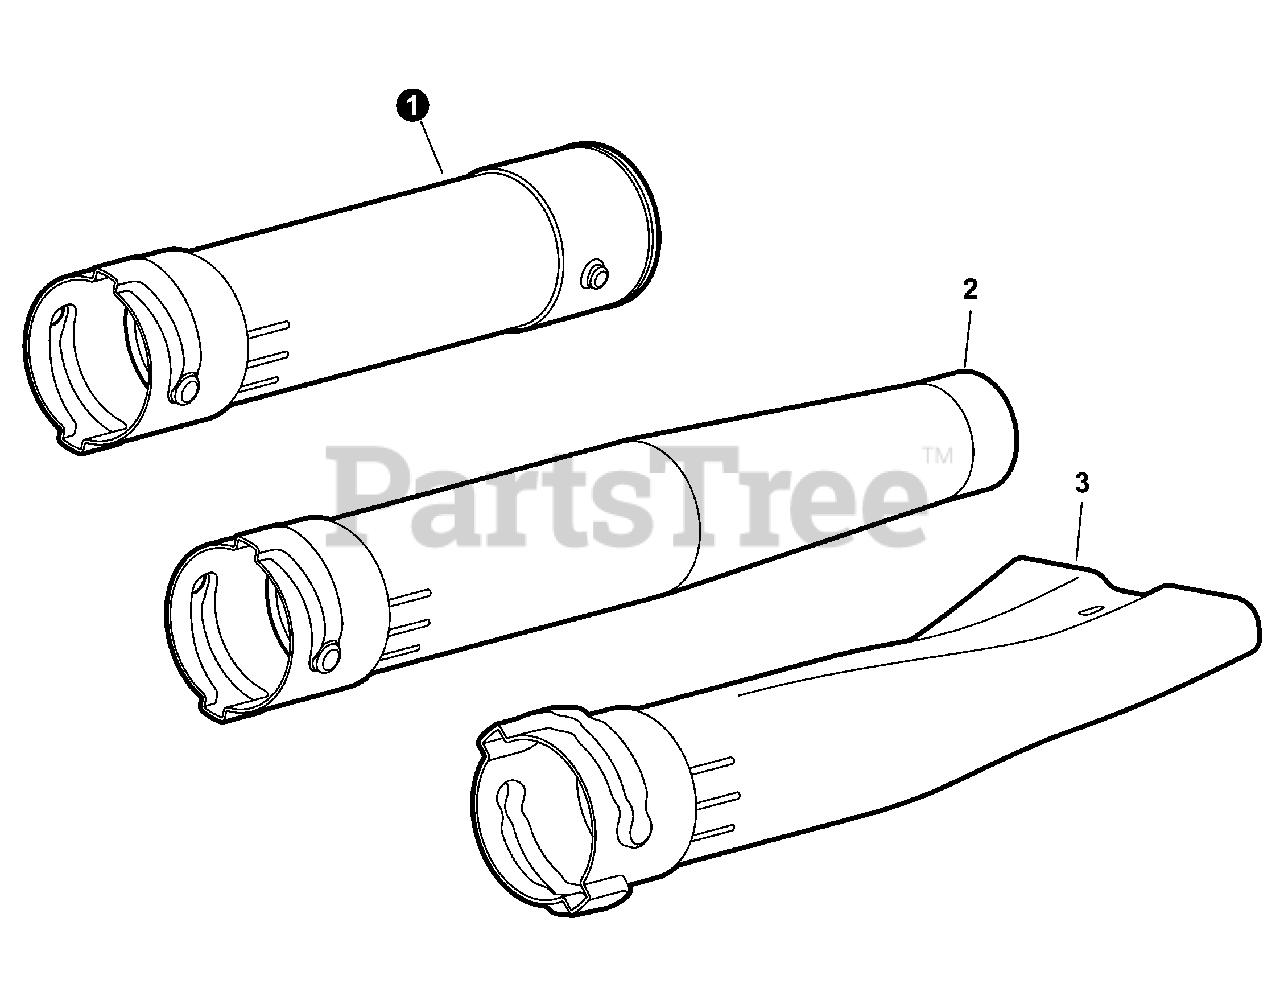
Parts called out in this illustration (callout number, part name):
1	TUBE, BLOWER
2	TUBE, BLOWER - ROUND NOZZLE
3	NOZZLE, FAN TIP
